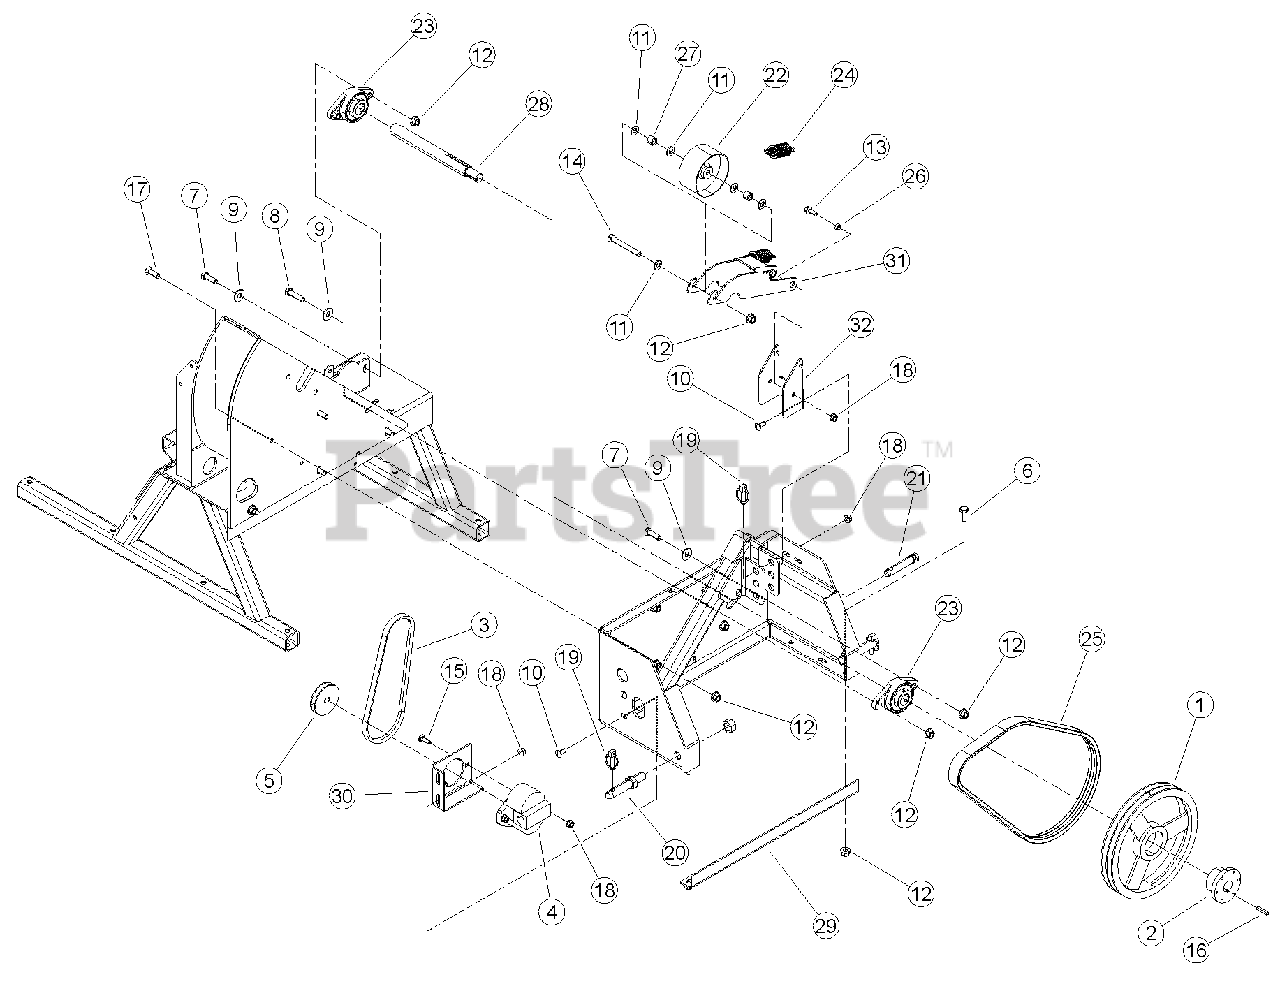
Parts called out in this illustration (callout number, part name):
1	SHEAVE, 2B12.4 SK
2	BUSHING, SK 1-1/4"
3	BELT, 4L350
4	PUMP, PTO HYDRAULIC FEED
5	PULLEY, 3-1/2 X 5/8 A
6	BOLT, 1/2 X 1-1/4" GR5 HHCS NC ZP
7	BOLT, 1/2 X 1-1/2 HEX HD GR5 ZP
8	BOLT, 1/2 X 2 GR5 HEX CAPSCREW ZP
9	WASHER, 1/2" FLAT ZP
10	BOLT, 3/8 X 1" GR5 CRG NC ZP
11	WASHER, 1/2" SAE FLAT ZP
12	NUT, 1/2-13 NYLOCK FLANGE
13	BOLT, 3/8 X 1 FLANGE NC
14	BOLT, 1/2 X 4 HEX CPS G5 ZP
15	BOLT, 3/8 X 1-1/4" GR5 CRG NC ZP
16	KEY, 1/4 SQ X 1-1/2 LG PLAIN
17	SCREW, 1/2 X 1-1/2 FLT HD SKT
18	NUT, 3/8-16 NYLOCK FLANGE
19	PIN, 7/16 X 1-3/4 LYNCH
20	PIN, LIFT ARM 7/8 X 5" LG
21	PIN, TOP LINK 3/4 X 4-1/2" LG
22	PULLEY, IDLER 5 X 2.50"
23	BEARING 1-1/4" DIA 2 BOLT FLANGE
24	SPRING, 1.25 OD X 3.50 LG X .148 WD
25	BELT, 2RBX56
26	SPACER, IDLER PIVOT
27	SPACER, .81 X .620
28	JACKSHAFT, PTO CHIPPER
29	BRACE, 3 PT BOTTOM
30	WELDMENT, PUMP MOUNT
31	ARM, INSIDE IDLER
32	BRACKET, INSIDE IDLER ARM MOUNTING
